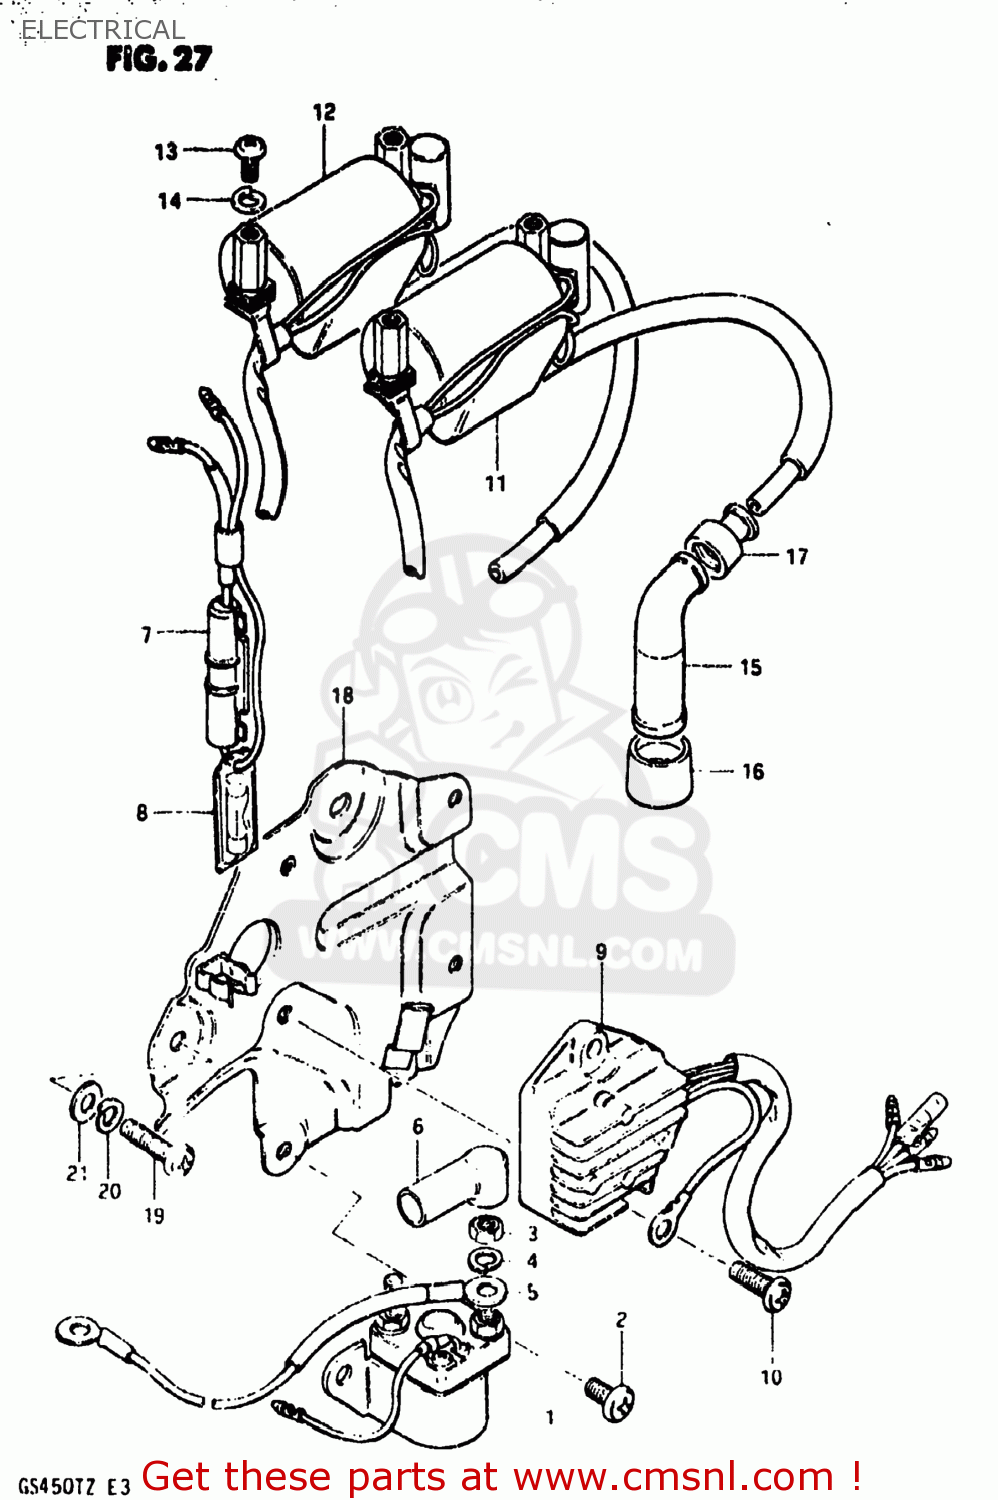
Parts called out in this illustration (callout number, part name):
1	RELAY ASSY,STARTING MOTOR
2	SCREW
3	NUT 6MM
4	LOCK WASHER
5	CORD,BATTERY MINUS
6	CAP,STARTER RELAY
7	BOX ASSEMBLY,FUSE
8	FUSE(15A)
9	RECTIFIER ASSEMBLY
10	SCREW
11	COIL ASSEMBLY,IGNITION
12	COIL ASSEMBLY,IGNITION
13	SCREW
14	LOCK WASHER
15	CAP,SPARK PLUG
16	SEAL,SPARK PLUG
17	SEAL,SPARK PLU
18	PLATE,ELECTRIC PARTS H
19	SCREW
20	LOCK WASHER
21	WASHER
